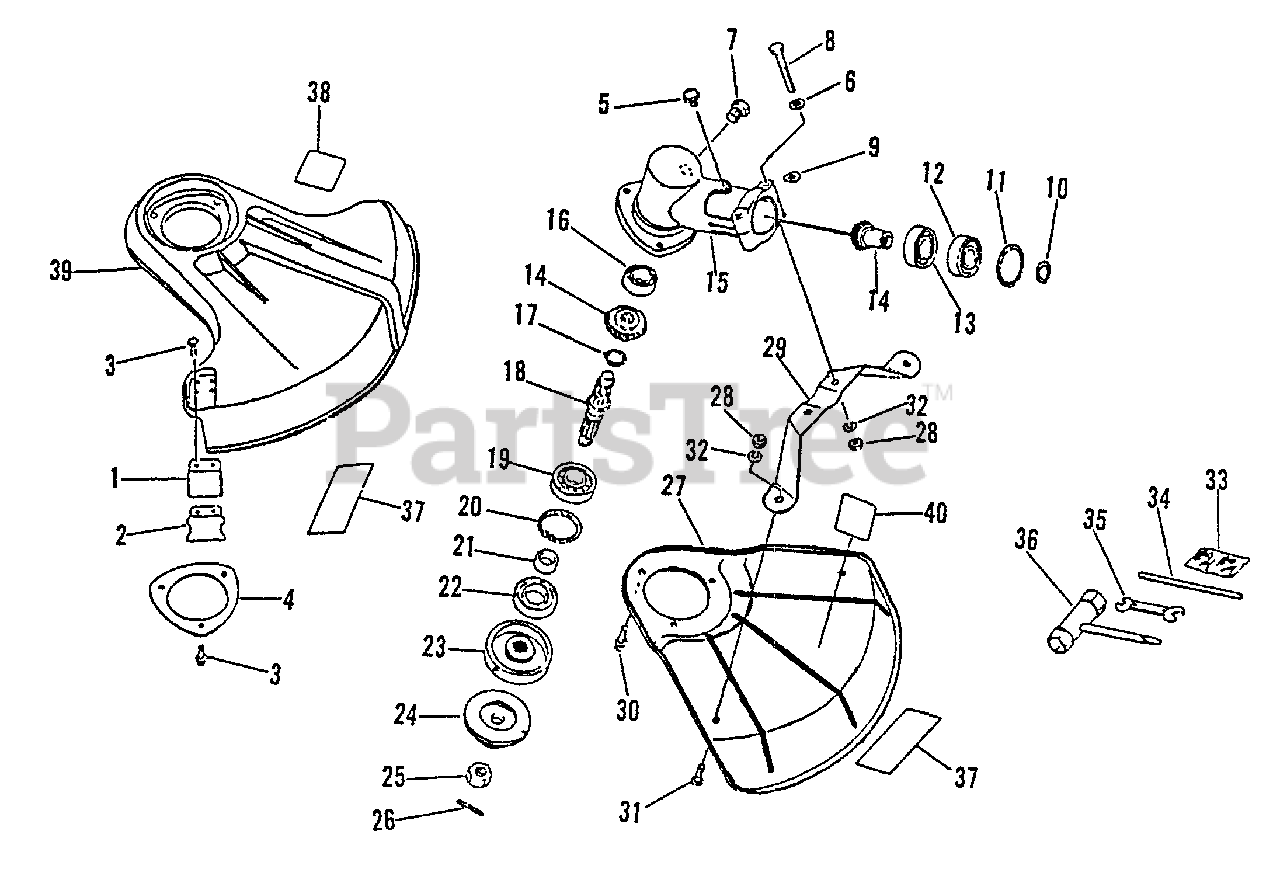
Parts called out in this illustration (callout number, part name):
1	KNIFE, TRIMMER LINE
2	GUARD
3	SCREW - 5X16
4	PLATE, SHIELD
5	SCREW - 5X10
6	WASHER - 5
7	BOLT - 8X8
8	BOLT - 5X40
10	RING, RETAINING - 12
11	RING, RETAINING - 28
12	BEARING, BALL - 6001
13	BEARING, BALL - 6001
14	GEAR SET - BEVEL
15	CASE, GEAR
16	BEARING, BALL - 6000
17	RING, RETAINING - 12
18	GEAR - SHAFT
19	BEARING, BALL - 6201
20	RING, RETAINING - 32
22	SEAL, OIL
23	ADAPTOR, BLADE - UPPER
24	ADAPTOR, BLADE - LOWER
25	NUT - 10 -- LEFT HAND
26	PIN, SPLIT - 2X22
27	DEBRIS SHIELD KIT
29	BRACKET, SHIELD
30	SCREW - 5X10
31	SCREW - 5X8
32	LOCKWASHER - 5
33	PIN, SPLIT - 2X22
34	LOCKING TOOL
35	SPANNER - 8X10mm
36	T-WRENCH - 17X19mm
37	LABEL - ECHO
38	LABEL - CAUTION
39	DEBRIS SHIELD KIT
40	LABEL - CAUTION
